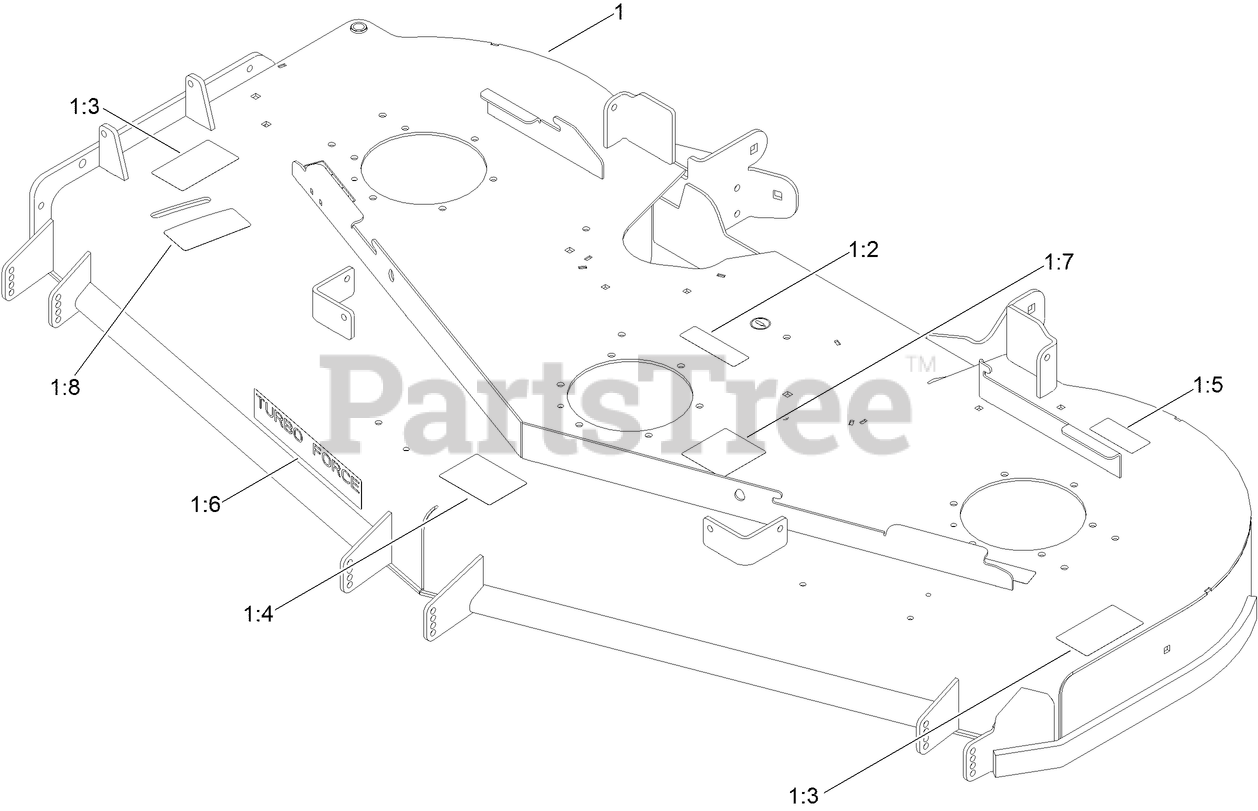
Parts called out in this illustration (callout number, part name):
1	DECK ASM
1:2	DECAL-COVER, MISSING
1:3	DECAL-DANGER
1:4	DECAL-SCALP, ANTI
1:5	DECAL-BOLT TORQUE
1:7	DECAL-ROUTING, DECK BELT
1:8	DECAL-ADJUSTMENT, BAFFLE
